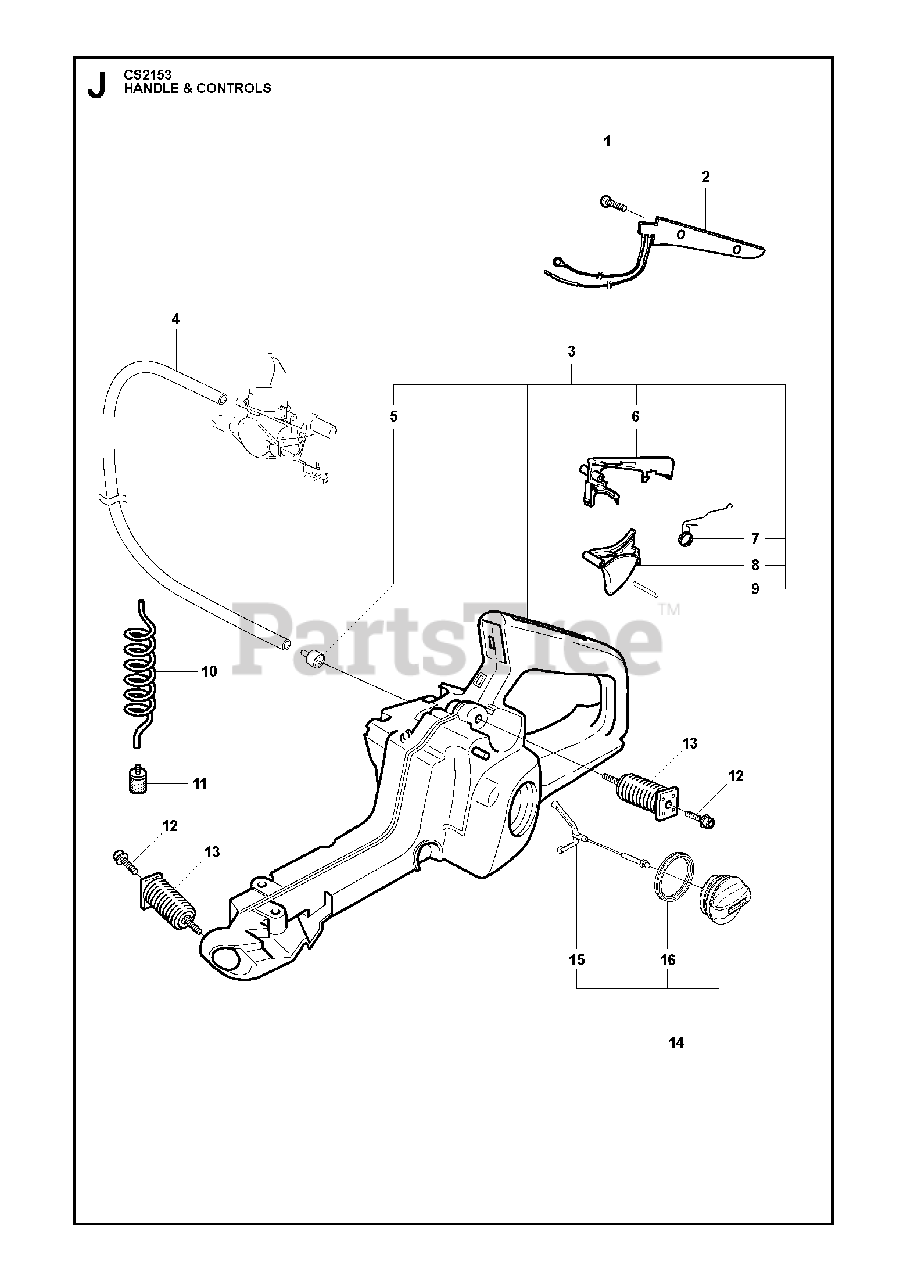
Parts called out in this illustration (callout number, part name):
1	SCREW
2	HANDLE CIRCUIT
3	TANK UNIT
4	FUEL HOSE
5	FUEL TANK VENT
6	THROTTLE LOCK
7	SPRING
8	THROTTLE TRIGGER
9	PIN
10	FUEL HOSE
11	FUEL FILTER
13	VIBRATION ABSORBER
14	TANK CAP
15	HOLDER
16	SEALING
